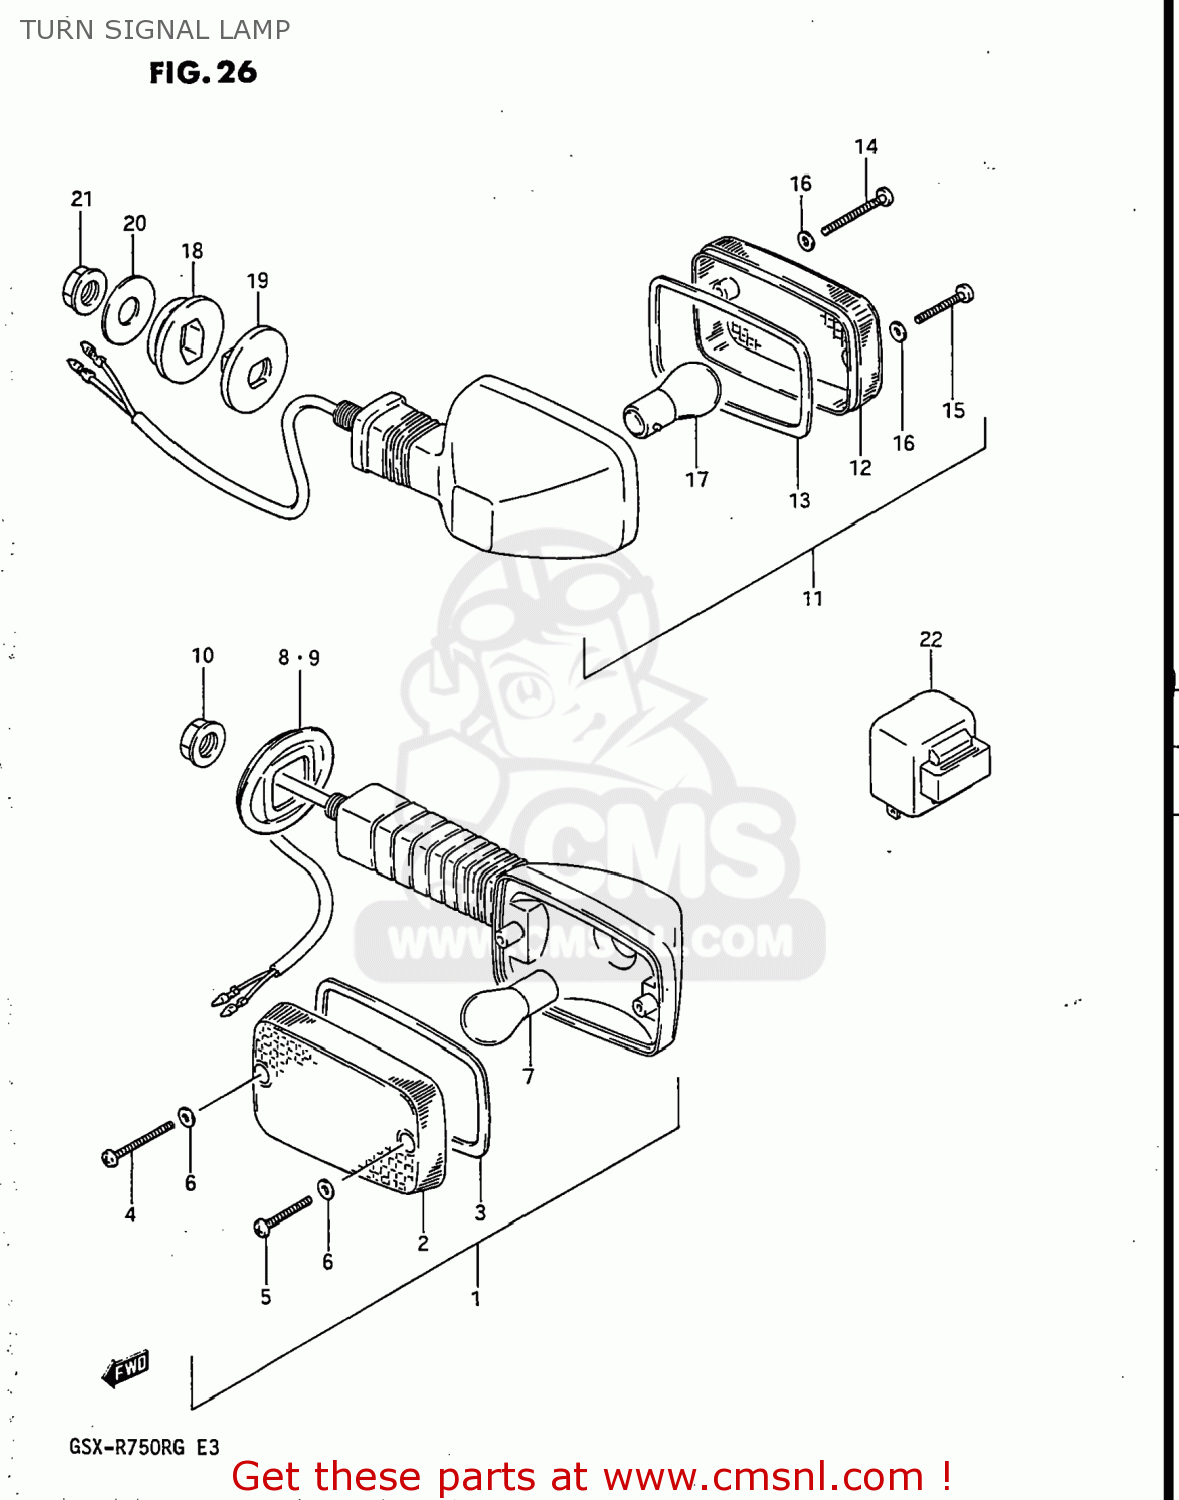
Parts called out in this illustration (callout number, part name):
1	LAMP ASSEMBLY,FRONT TURN SIGNAL
2	LENS,FR
3	GASKET (NAS)
4	SCREW,TURN SIG LENS FITTING
5	SCREW
6	GASKET (NAS)
7	BULB(12V23W,STANLEY,A4577A)
8	GROMMET,TURNSIGNAL LAMP,R
9	GROMMET,TURNSIGNAL LAMP,L
10	NUT
11	LAMP ASSEMBLY,REAR TURN SIGNAL
12	LENS,RR
13	GASKET (NAS)
14	SCREW,TURN SIG LENS FITTING
15	SCREW
16	GASKET (NAS)
17	BULB(12V23W,STANLEY,A4577A)
18	CUSHION
19	SPACER
20	SPACER
21	NUT
22	RELAY ASSEMBLY,TURN SIGNAL
